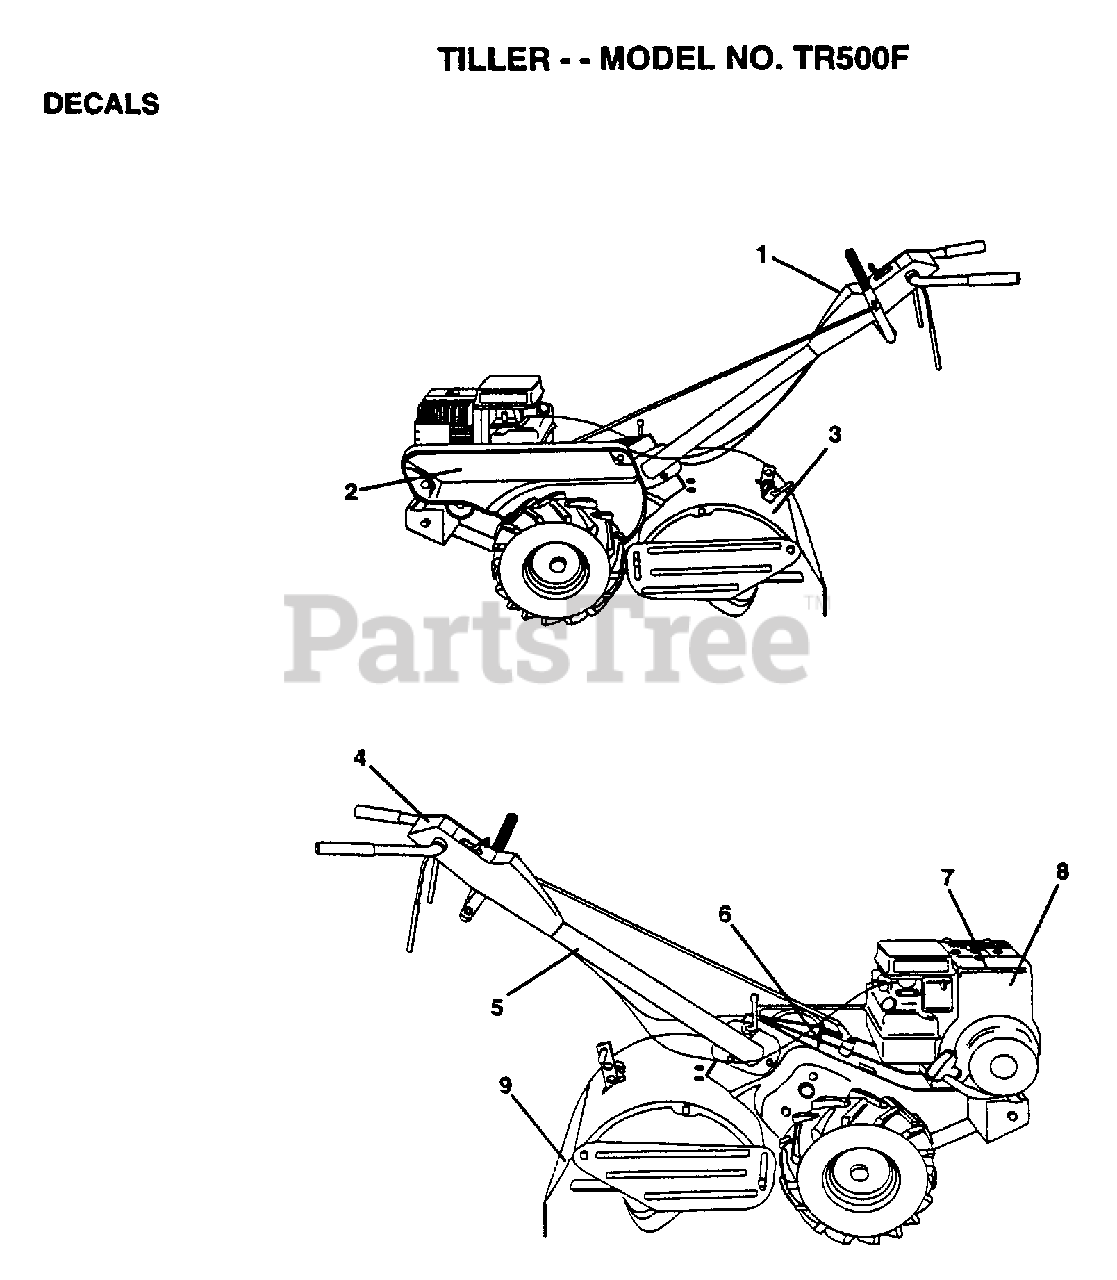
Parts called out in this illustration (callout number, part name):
1	DECAL.PNL.CONTROL
3	DECAL.SHLD.TINE
4	DECAL.INSTRUCTION
5	DECAL TI
6	DECAL CRT
8	DECAL, BRIGGS & STRATTON
9	DECAL TI
